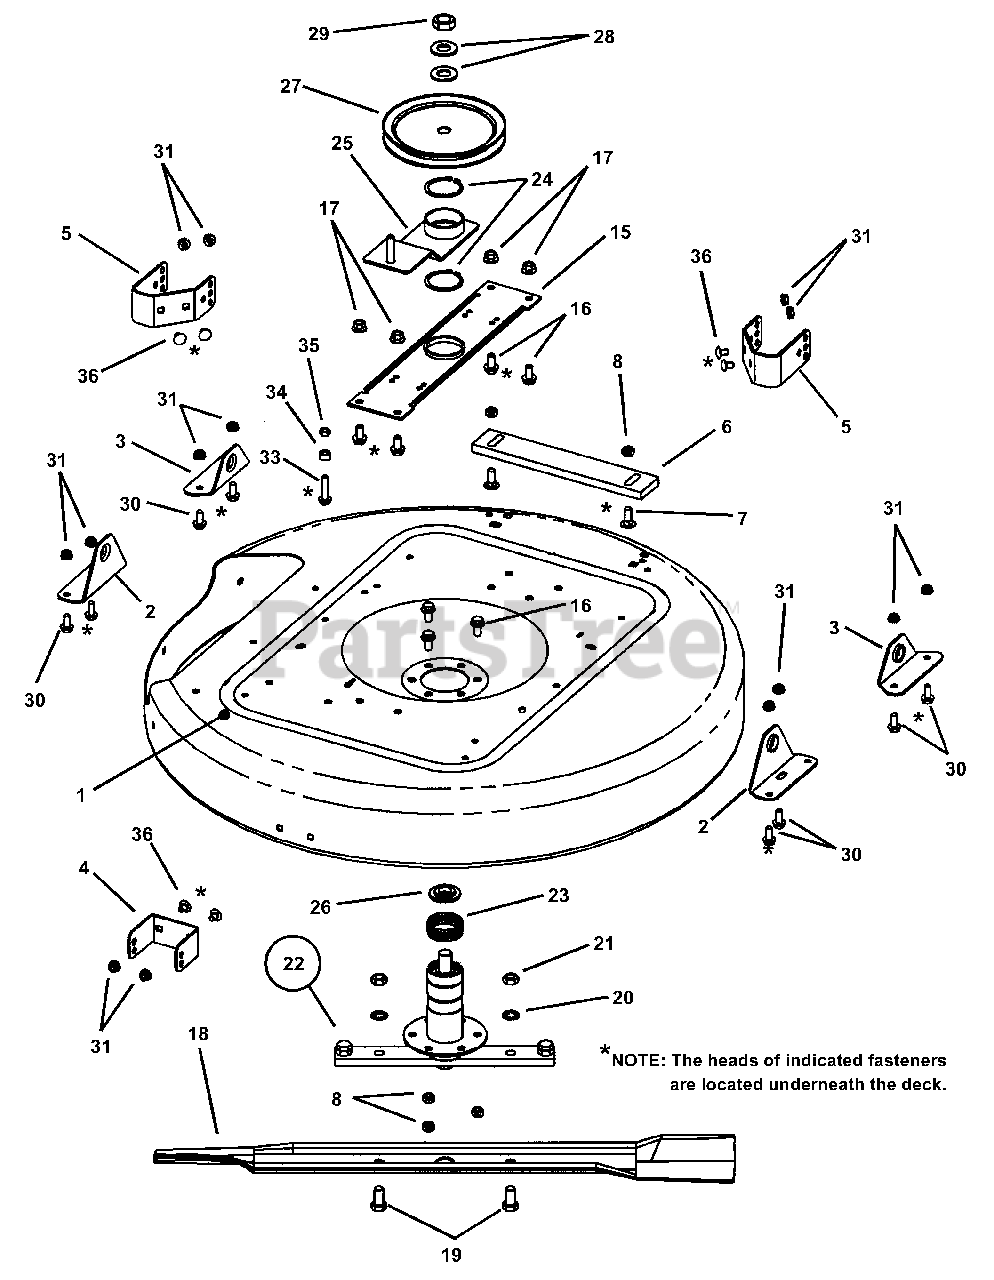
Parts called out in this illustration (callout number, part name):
1	DECK, 33" Replacement Structure
2	BRACKET, Deck Lift Slotted
3	BRACKET, Deck Lift
4	BRACKET, Anti-Scalp Adj. Front
5	BRKT., Anti-Scalp Adj. Side
6	BAR, Weight Rear
7	BOLT, 3/8-16 x 1" Carriage
8	NUT, 3/8-16 Hex Center Lock
15	BRACE, Spindle
16	BOLT, 3/8-16 x 3/4" Hex Flange Lock, Grade 5
17	NUT, 3/8-16 Hex Flange Lock
18	BLADE, 33" High Lift
19	SCREW, 1/2-20 x 1" Hex Head Cap, Grade 5
20	WASHER, 1/2" Internal Tooth Lock
21	NUT, 1/2-20 Hex Jam
22	ASSEMBLY, Spindle
23	RING, 2" Tolerance
24	RING, 2" External Retaining
25	ARM, Idler (weldment)
26	WASHER, Spindle
27	PULLEY, Spindle 7" O.D.
28	WASHER, 25/32" Flat
29	NUT, 3/4-16 Hex Jam, Grade 8
30	BOLT, 5/16-18 x 3/4" Hex Flange Lock
31	NUT, 5/16-18 Hex Fl. Lock
33	BOLT, 5/16-18 x 1-1/2" Hex Flange Lock, Grade 5
34	SPACER, 11/32"
35	NUT, 5/16-18 Hex Lock
36	BOLT, 5/16-18 x 1/2" Short Neck Carriage
